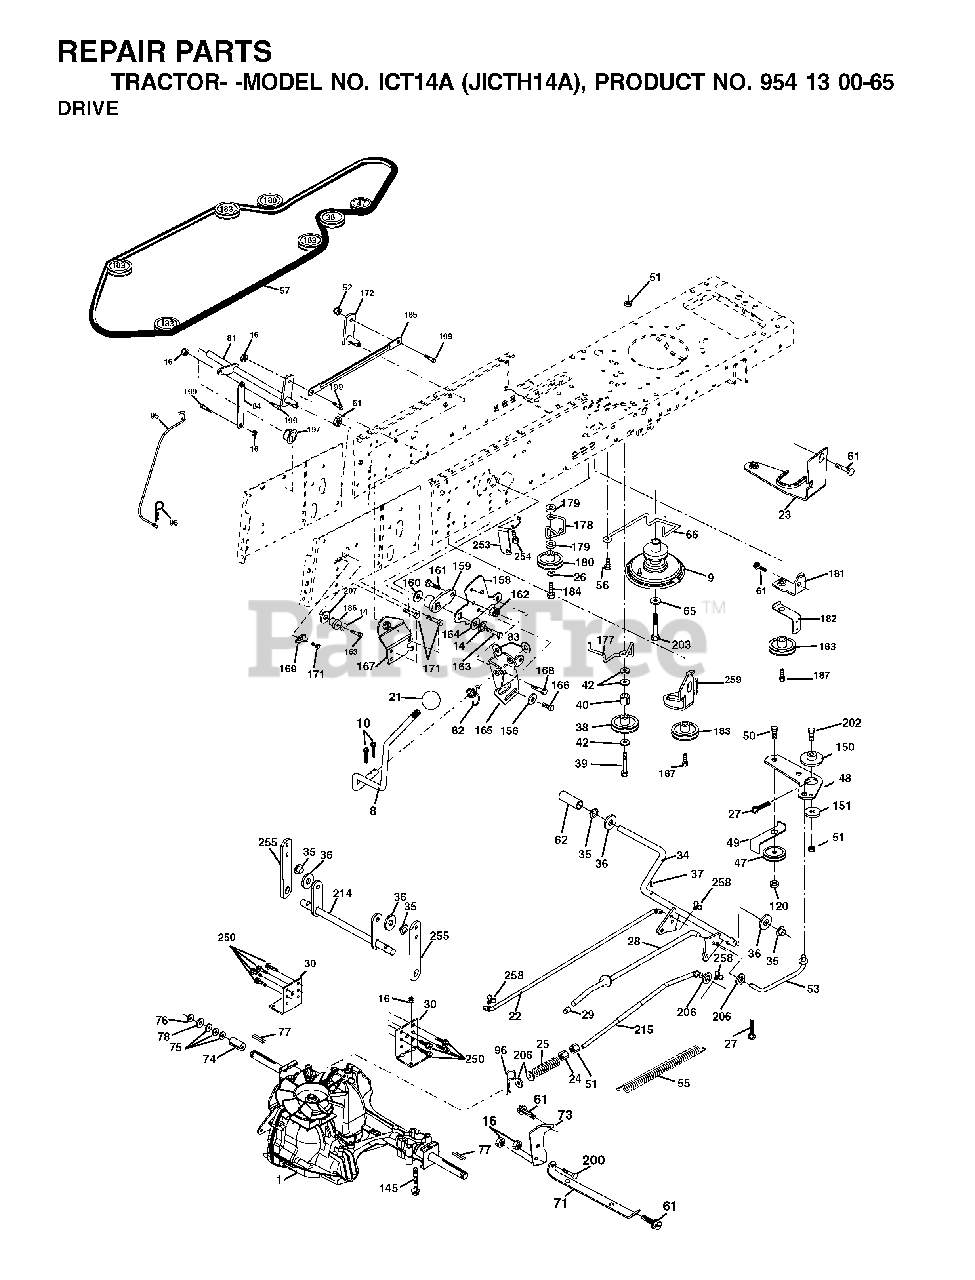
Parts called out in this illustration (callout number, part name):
8	ROD SHIFT
9	CLUTCH ASSY
10	PIN COTTER
14	LOCKWASHER
16	NUT.71038.31-18.HEX.NYLOCK
21	KNOB.DELUXE.(PISTOL.GRIP).BLAC
24	NUT
25	SPRING ROD LT
27	COTTER PIN
28	ROD, PARKING BRAKE
29	PLUNGER CAP
30	BRKT, TRNSXLE MNT 20"
34	SHAFT, FOOT PEDAL
35	BEARING.NYLON
36	WASHER LT
37	DRIVE PIN
38	PULLEY.FLAT
42	WASHER
47	IDLER PULLEY
48	BELLCRANK, CLUTCH
49	RETAIN BELT
50	BOLT
51	LOCKNUT
52	LOCKNUT
53	LINK, CLUTCH LT
55	SPRING, RETURN LT
56	SCREW.3/8-16
61	SCREW 3/8-16X3/4
62	PEDAL COVER T
65	LOCKWASHER
66	KEEPER BELT ENGINE
71	STRAP TORQUE LH HYDRO
73	STRAP TORQUE RH HYDRO
74	SPACER AXLE
76	E-RING LT
77	SQUARE KEY
81	SHAFT ASSY
82	SPRING,TORSION
83	WASHER
96	RETAINER M
120	NUT LOCK FLG 3/8-16 UNC
145	BOLT HEX 5/16-18 GR 5
150	BUSHING.BELLCRANK.GRD.DR
151	WASHER 12/32X2X10GA
156	WASHER.SRRTD.5/16
158	BRACKET
159	HUB
161	BOLT
162	NUT.CROWNLOCK.1/4
165	RP BRACKET
167	BRACKET
168	BOLT.SHOULDER.5/16-18X
169	PLATE.FASTENING.CROSS.SHAFT
180	PULLEY.FLAT.IDLER
182	KEEPER BELT
184	SCREW.HXWSH.3/8
187	BOLT.5/16-18X1.25
197	NYLINER SNAP 5/8" ID
199	BOLT SHOULDER 5/16-18 UNC
200	BOLT
202	BOLT.3/8-16X1.50
206	WASHER
207	WASHER NYL
250	SCREW 3/8-16X3/4
258	CLIP RETAINER
